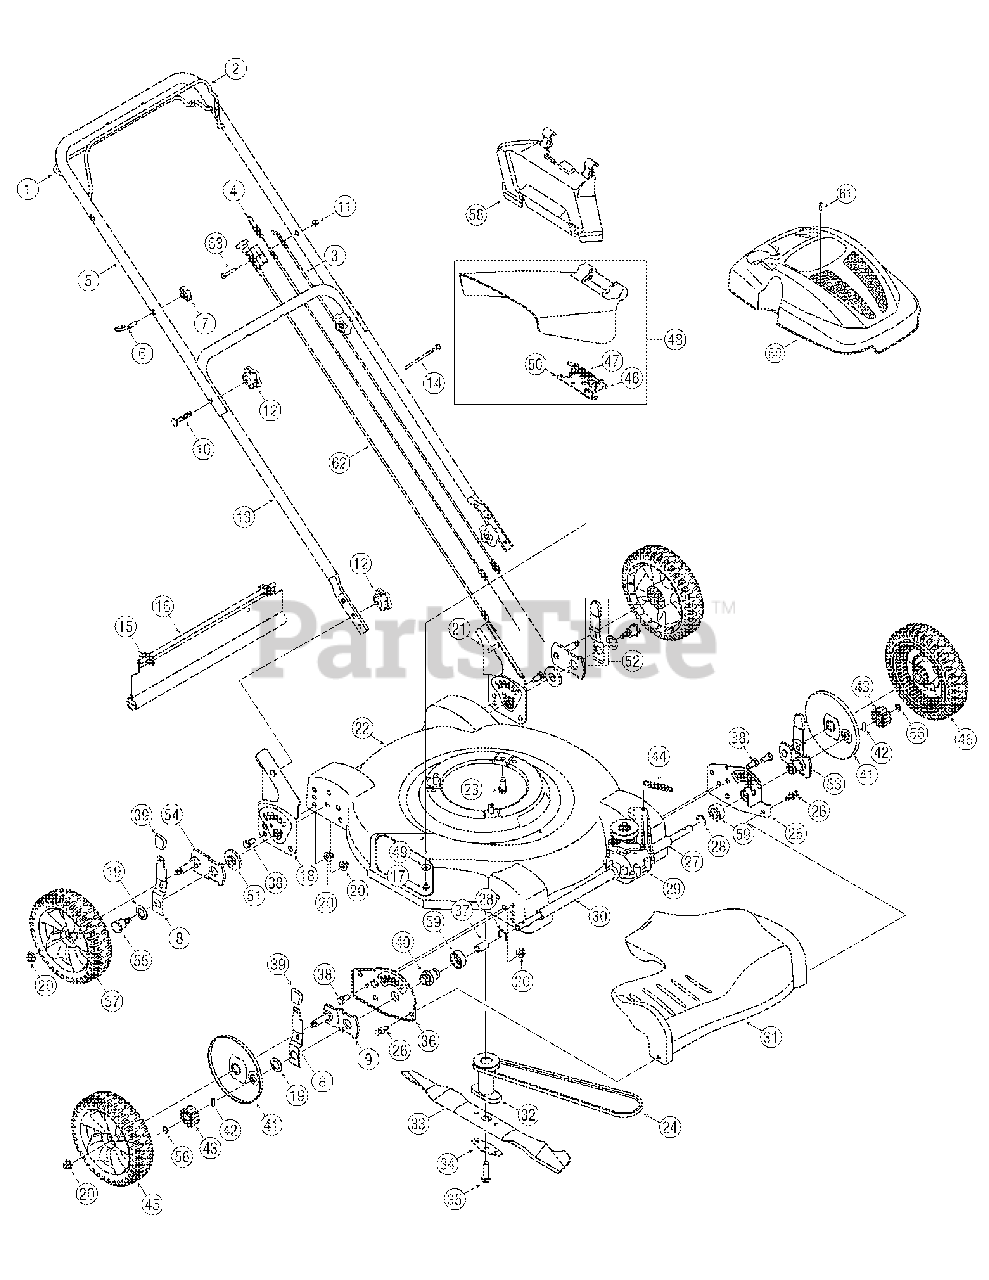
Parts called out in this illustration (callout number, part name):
1	Drive Control
3	Blade Control Cable
4	Drive Control Cable
6	Eye Bolt
7	Wing Nut, 1/4-20
8	Spring Lever
9	Pivot Arm Assembly
10	Carriage Bolt, 5/16-18 x 2.0
11	Flange Lock Nut, 1/4-20
12	Star Knob
14	Cable Tie
15	Hinge Clip
16	Trail Shield
17	Hex Screw, 1/4-20 x.500
20	Lock Nut, 3/8-16
23	Hex Washer Scr., 3/8-16
24	V-Belt, 3L x 32.90
26	Rivet
27	Sleeve Spacer, .550 ID x 2.22
28	Retainer Ring
29	Transmission Assy. Comp.
30	Sleeve Spacer, .550 ID x 8.51
31	Transmission Cover
32	Blade Adapter
33	22" Mulching Blade
34	Bell Blade Support
35	Hex Cap Screw, 3/8-24 x 1.5
37	Slv. Bearing, .502 x.627 x 1.00
38	Hex Cap Screw, 3/8-16 x .75
39	Adjustment Knob
40	Bearing Support
41	Wheel Dust Cover
42	Pin
43	Spur Gear 14T - RH
43	Spur Gear 14T - LH
44	Ext. Spring, .47 OD x 2.50
45	Front Wheel 8 x 1.8
46	Hinge Pin
47	Torsion Spring
48	Side Discharge Assembly
49	Bell Washer, .265 ID x. 75 OD
50	Deflector Chute Adapter
51	Height Adjustment Bearing
52	Rear Hgt. Adj. Lever Assembly
53	Front Lever Assembly
54	Rear Pivot Arm Assembly
55	Shoulder Screw, 3/8-16
56	Screw 1/4-20 X .39
57	Rear Wheel 8 x 1.8
58	Mulching Baffle
59	Bearing Support Spacer
60	Engine Shroud (Yellow)
61	Machine Screw, M4X.7
62	Choke Cable
63	Hex Screw, 1/4-20 x 1.50
